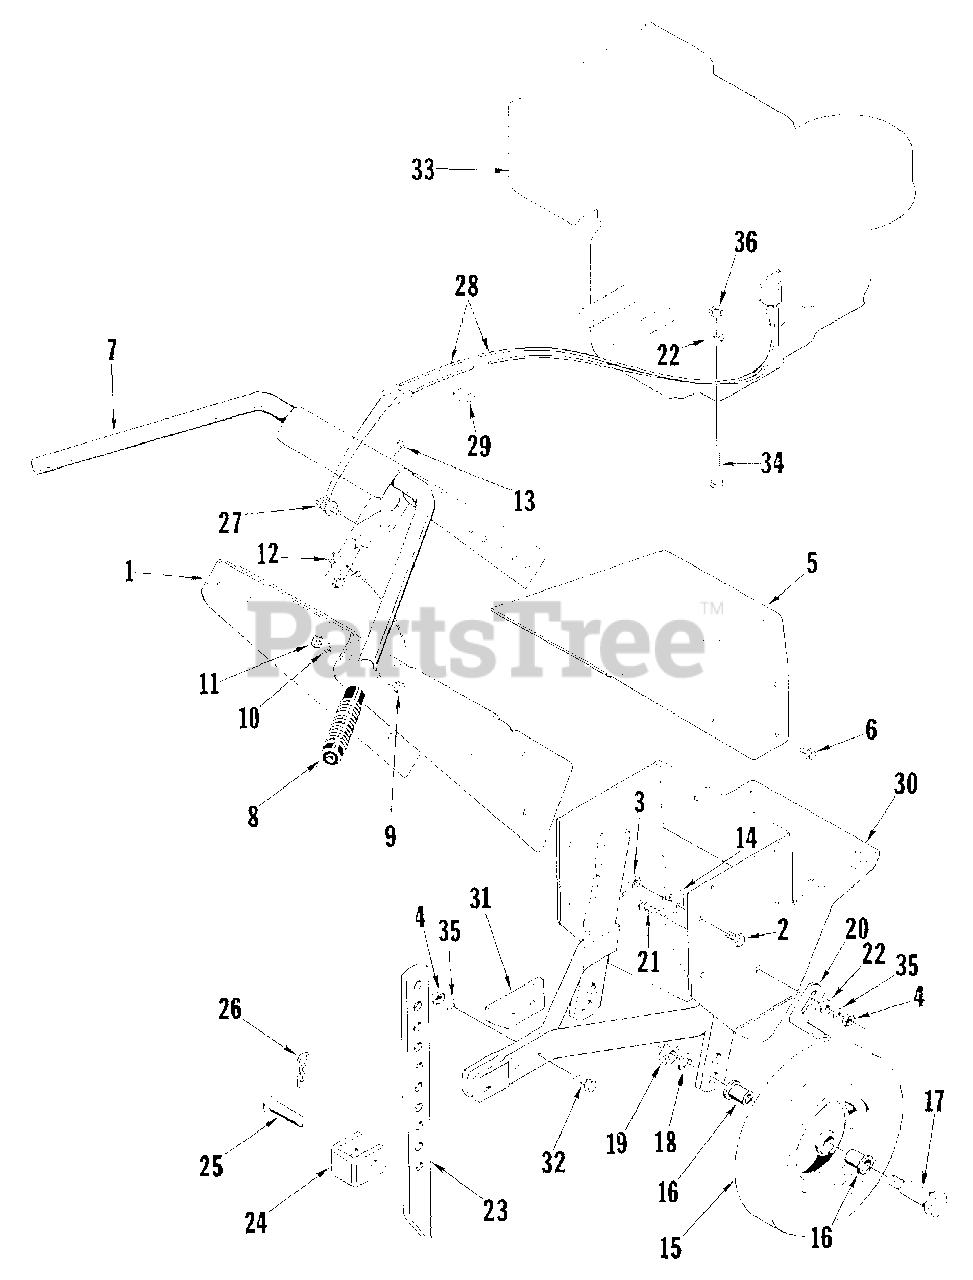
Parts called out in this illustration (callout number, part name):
1	CHANNEL, Handle Bar Support
2	SCREW, Hex, Lock, Cap, 3/8-16 x 1"
3	NUT, Hex, Lock, 3/8-16
4	NUT, Hex, Full, 3/8-16
6	SCREW, Hex, 1/4-20 x 3/8
7	CHANNEL, Handle Bar
8	GRIP, Handle
9	SCREW, Hex, Lock, Cap, 5/16-18 x 3/4
10	WASHER, Lock, 5/16"
11	NUT, Hex, Full, 5/16-18
12	CONTROL, Throttle
13	SCREW, Self Tapping, 1/4-20 x 1/2"
15	WHEEL & TIRE
16	BUSHING, Wheel
17	BOLT, Shoulder
18	WASHER, Lock, 1/2"
19	NUT, Hex, Full, 1/2-13
21	BOLT, Carriage, 3/8-16 x 1"
22	WASHER, Plain, 5/16"
26	CLIP, Spring
28	IGNITION, Interlock
30	FRAME ASSEMBLY
32	SCREW, Hex Cap, 3/8-16 x 1-1/2"
33	ENGINE, 8 HP
34	SCREW, Hex Cap, 5/16-18 x 1-3/4"
35	WASHER, Lock, 3/8"
36	NUT, Hex, Lock, 5/16-18
